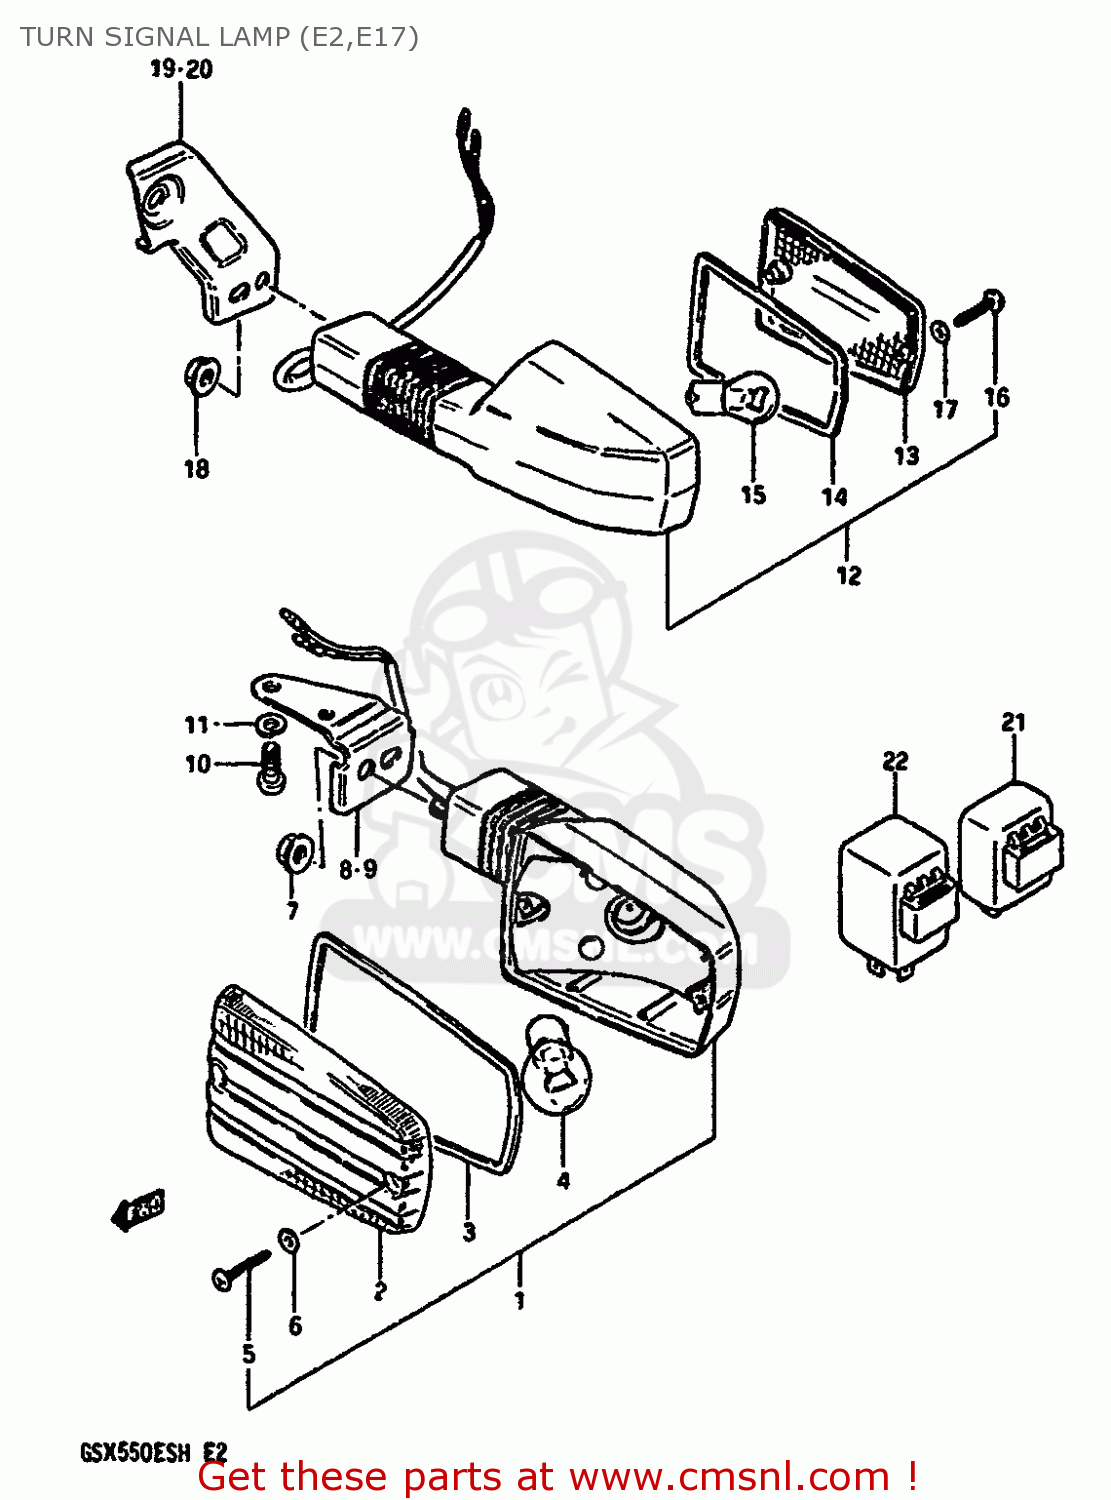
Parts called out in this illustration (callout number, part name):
1	LAMP ASSY, FRONT TURN SIGNAL
2	LENS
3	GASKET (NAS)
4	BULB(12V21W)
5	SCREW
6	GASKET (NAS)
7	NUT M8
8	BRACKET,FRONT TURN SIGNAL
9	BRACKET,FRONT TURN SIGNAL
10	SCREW
11	WASHER,LOCK
12	LAMP ASSY,REAR TURN SIGNAL
13	LENS
14	GASKET (NAS)
15	BULB(12V21W)
16	SCREW
17	GASKET (NAS)
18	NUT
19	BRACKET,REAR TURN SIGNAL
20	BRACKET,REAR TURN SIGNAL
21	RELAY ASSEMBLY,TURN SIGNAL
22	RELAY ASSY,TUR
